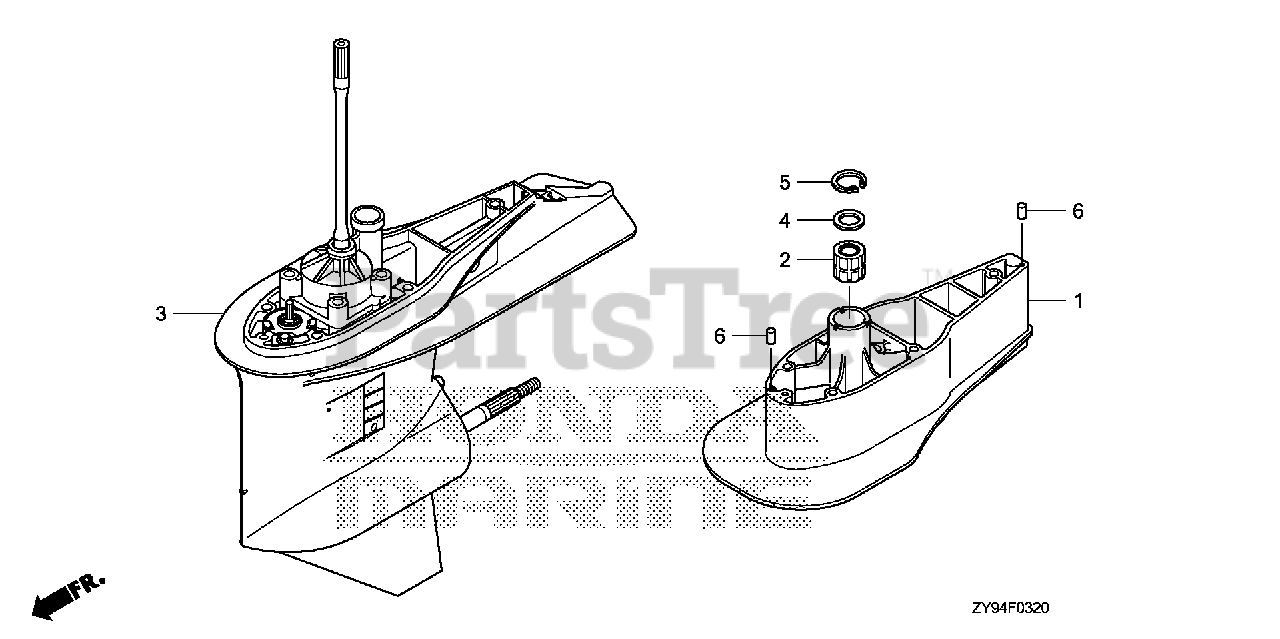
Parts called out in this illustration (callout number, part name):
1	SEPARATOR, EXTENSION *NH282MU* (XL) (OYSTER SILVER METALLIC-U)
2	BUSH, VERTICAL SHAFT
3	CASE ASSY., GEAR *NH282MU* (OYSTER SILVER METALLIC-U)
4	WASHER (26MM)
5	CIRCLIP (INNER) (40)
6	PIN, DOWEL (6X10)
